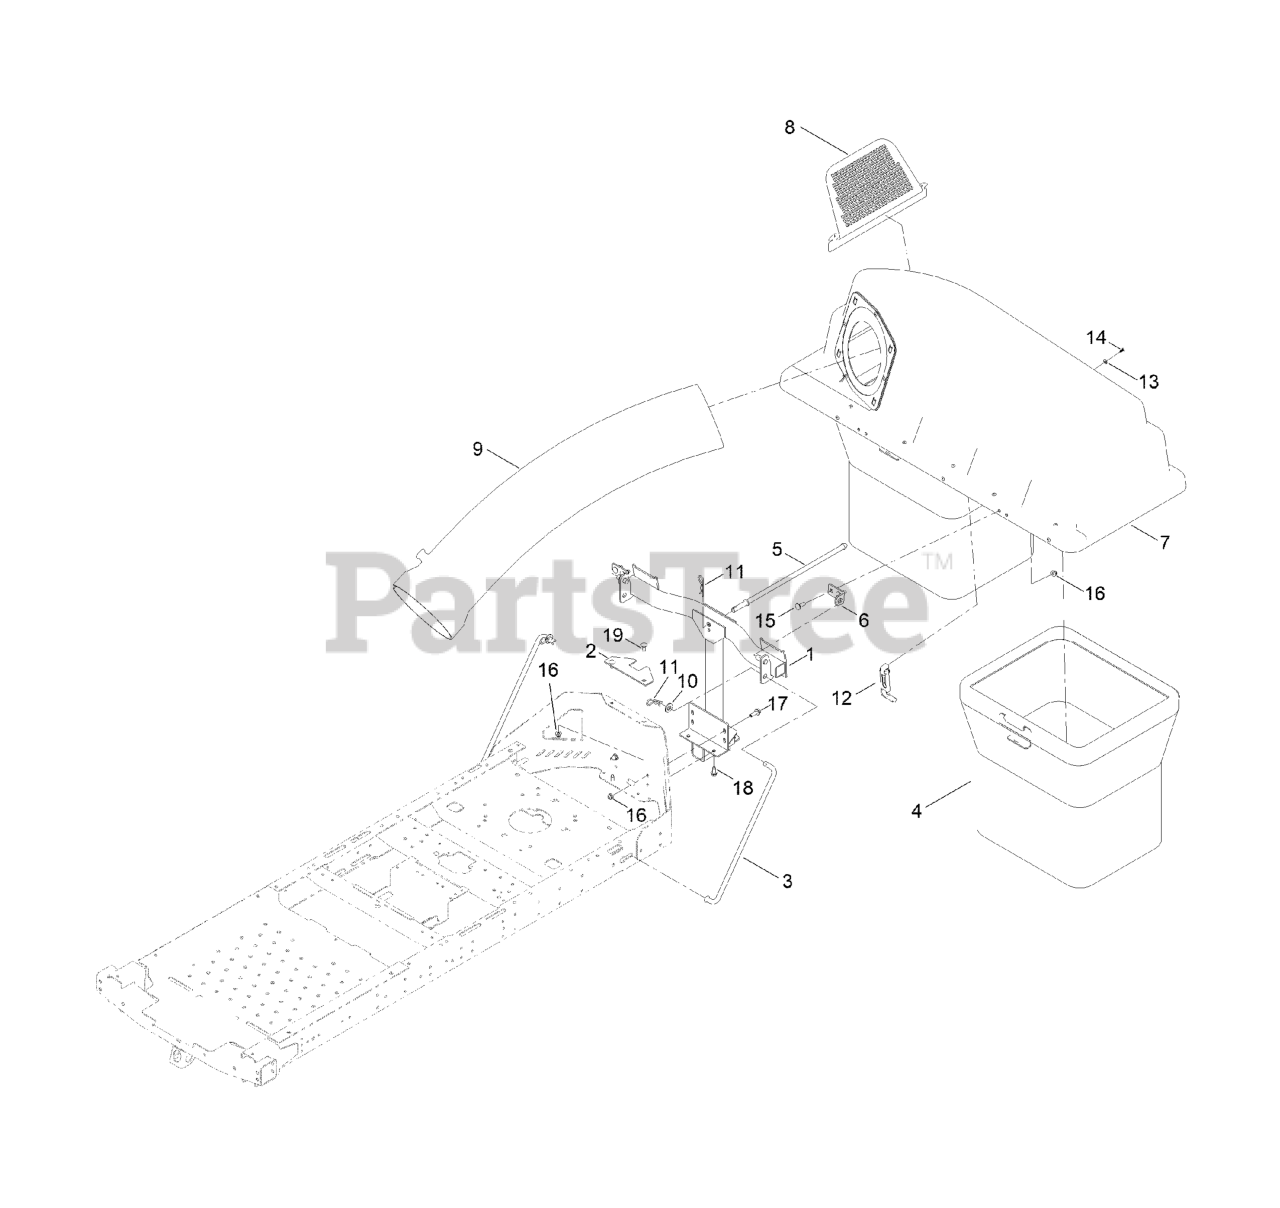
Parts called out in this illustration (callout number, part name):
1	Frame ASM, Pivot [black]
2	BRACKET-STABILIZER
3	ROD-SUPPORT, CZ
4	Bag ASM
5	ROD-HOOD, DOWN (HOLD)
6	BRACKET-HOPPER PIVOT
7	Top ASM-Bagger
8	SCREEN-BAGGER
9	TUBE-BAGGER
10	WASHER-FLAT
11	PIN-HAIR
12	LATCH-RUBBER
13	Washer-Plain
14	SCREW-PLASTIC, PTH
15	Bolt-CARR
17	SCREW-HHF
18	Screw-HWH 5/16-18 X 3/4 Tf
19	BOLT-CARR
